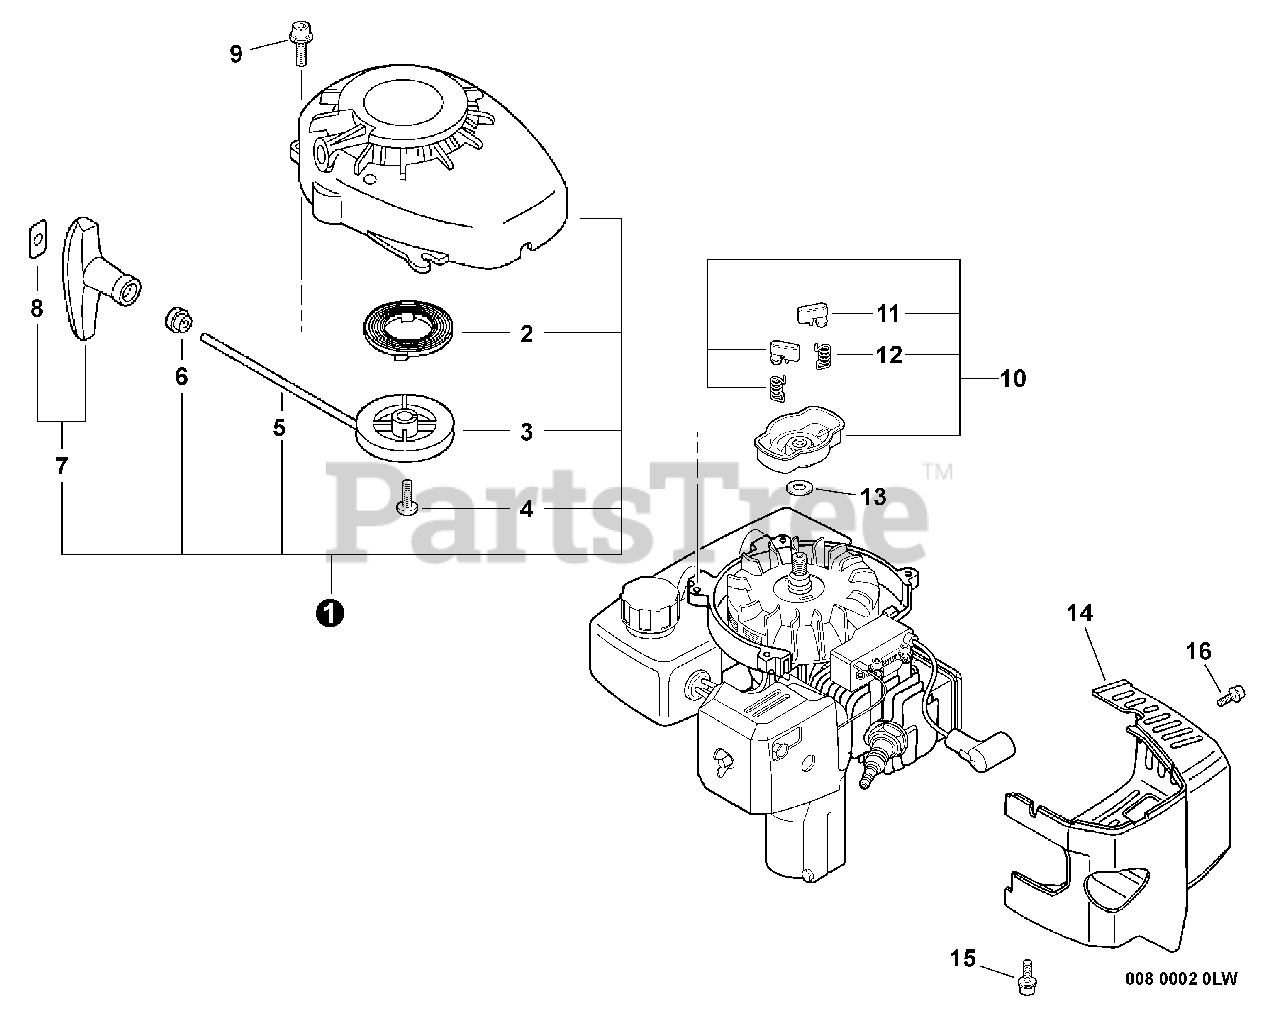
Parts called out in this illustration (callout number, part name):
1	STARTER ASSY
2	SPRING, RECOIL
3	REEL, ROPE
4	SCREW
5	ROPE, STARTER
6	GUIDE, ROPE
7	GRIP, STARTER
8	RETAINER, ROPE
9	SCREW 4×16
10	PAWL ASSY, STARTER
11	PAWL, STARTER - BLACK
12	SPRING, RETURN
13	WASHER, SPRING 8
14	COVER, ENGINE
15	SCREW 4×18
16	BOLT 4×8
